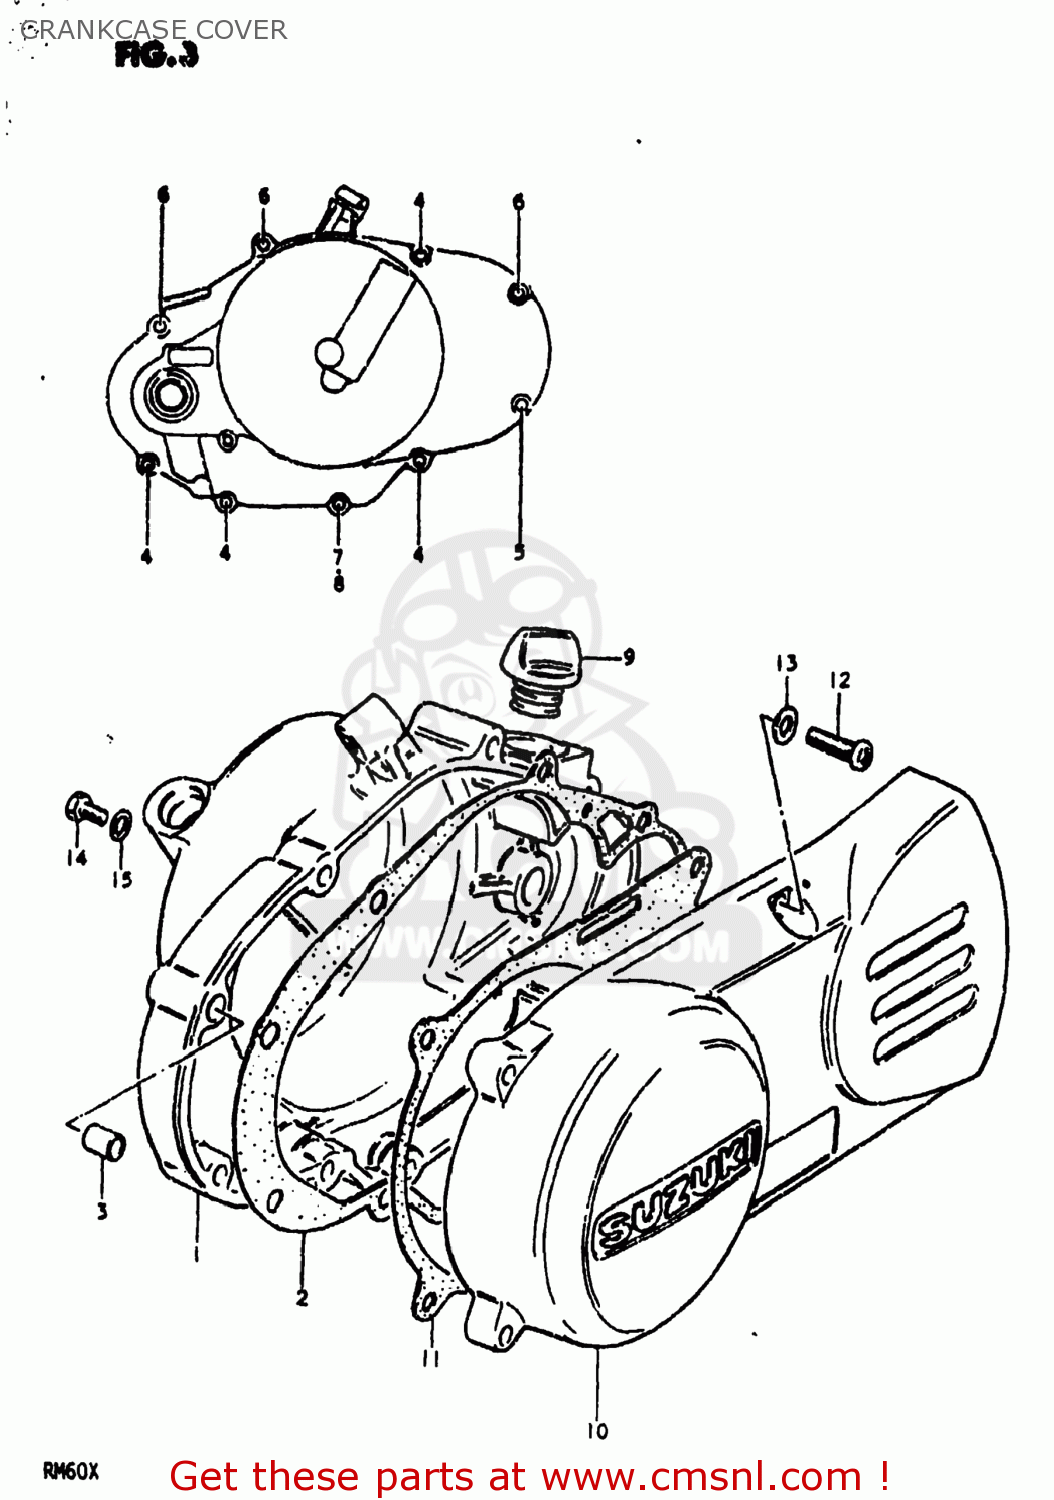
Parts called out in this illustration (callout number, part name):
1	COVER,CLUTCH
2	GASKET,CLUTCH COVER (MCA)
3	PIN
4	SCREW
5	SCREW 6X30
6	SCREW
7	SCREW (6X35)
8	GASKET(6.2X11X1).2 (NAS)
9	PLUG
10	COVER,MAGNETO
11	GASKET,MAGNETO COVER (NAS)
12	SCREW
13	WASHER
14	SCREW(6X10)
15	GASKET(6.2X11X1) (NAS)
